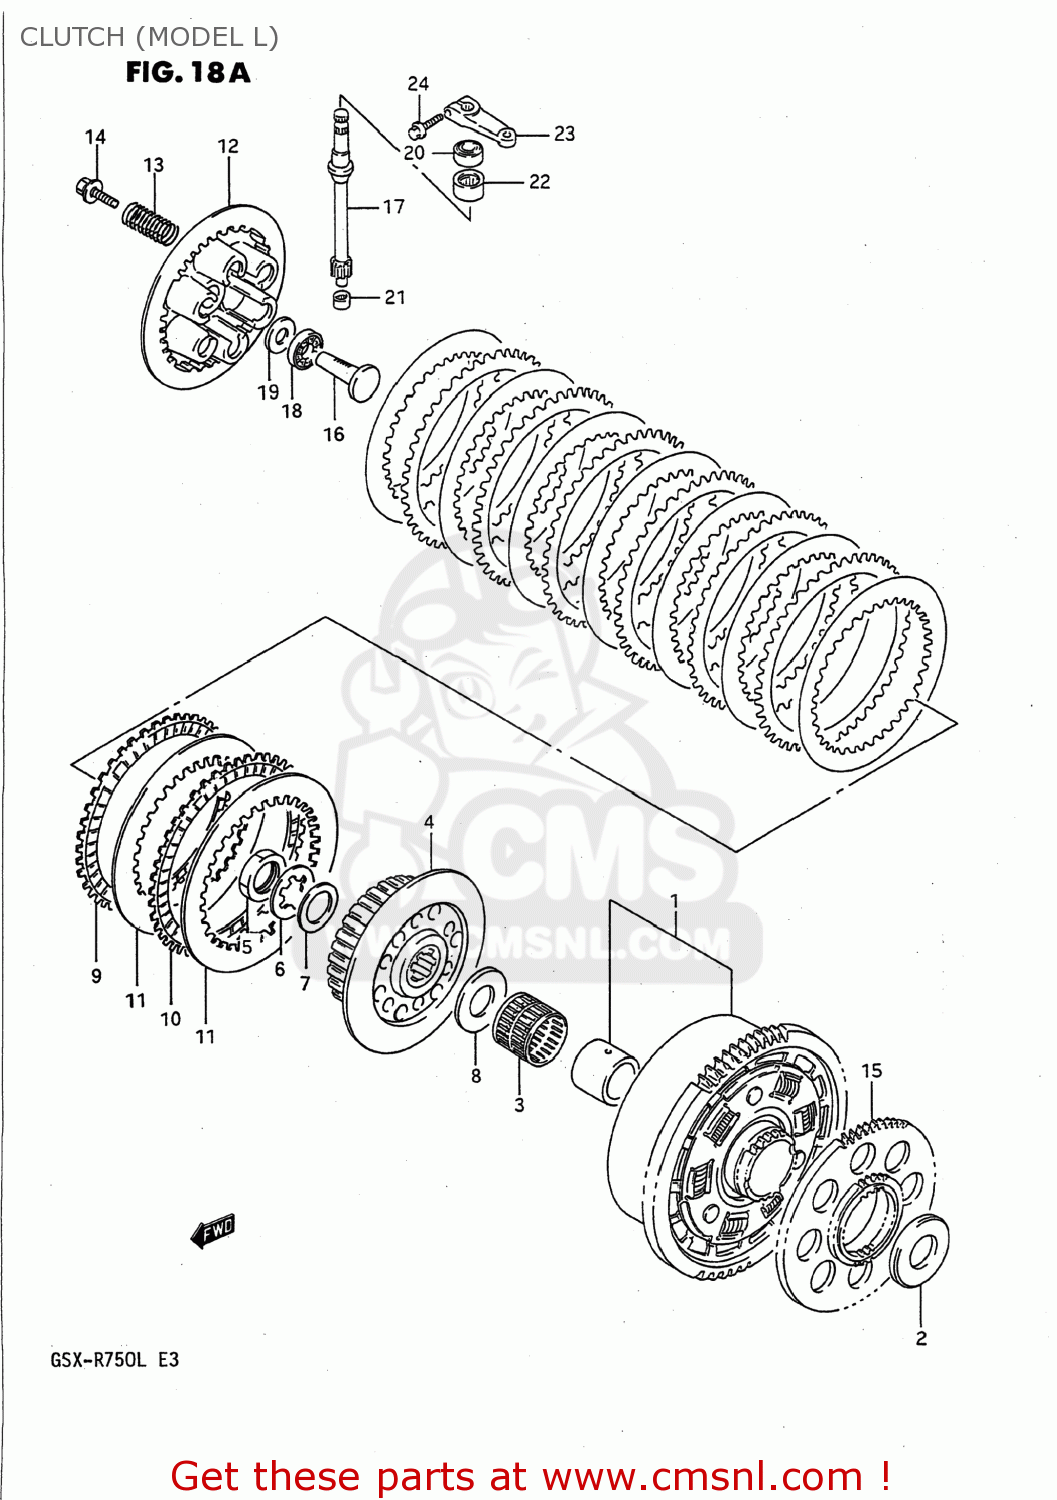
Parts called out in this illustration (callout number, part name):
1	GEAR ASSEMBLY,PRIMARY DRIVE
2	WASHER(25X54X2.5)
3	BEARING(35X40X35.8)
4	HUB,CLUTCH SLEEVE
5	NUT
6	WASHER,LOCK
7	WASHER
8	WASHER(25X50X2.5)
9	PLATE,CLUTCH DRIVE (NAS)
10	PLATE,CLUTCH DRIVE NO.2 (NAS)
11	PLATE,CLUTCH DRIVEN (NAS)
12	DISC,CLUTCH PRESSURE
13	SPRING
14	BOLT(6X25)
15	GEAR,GENERATOR DRIVE
16	RACK,CLUTCH RELEASE
17	PINION,CLUTCH RELEASE
18	BEARING(15X28X2)
19	WASHER
20	OIL SEAL
21	BEARING 10X14X10
22	BEARING(15X22X12)
23	ARM,CLUTCH RELEASE
24	BOLT
